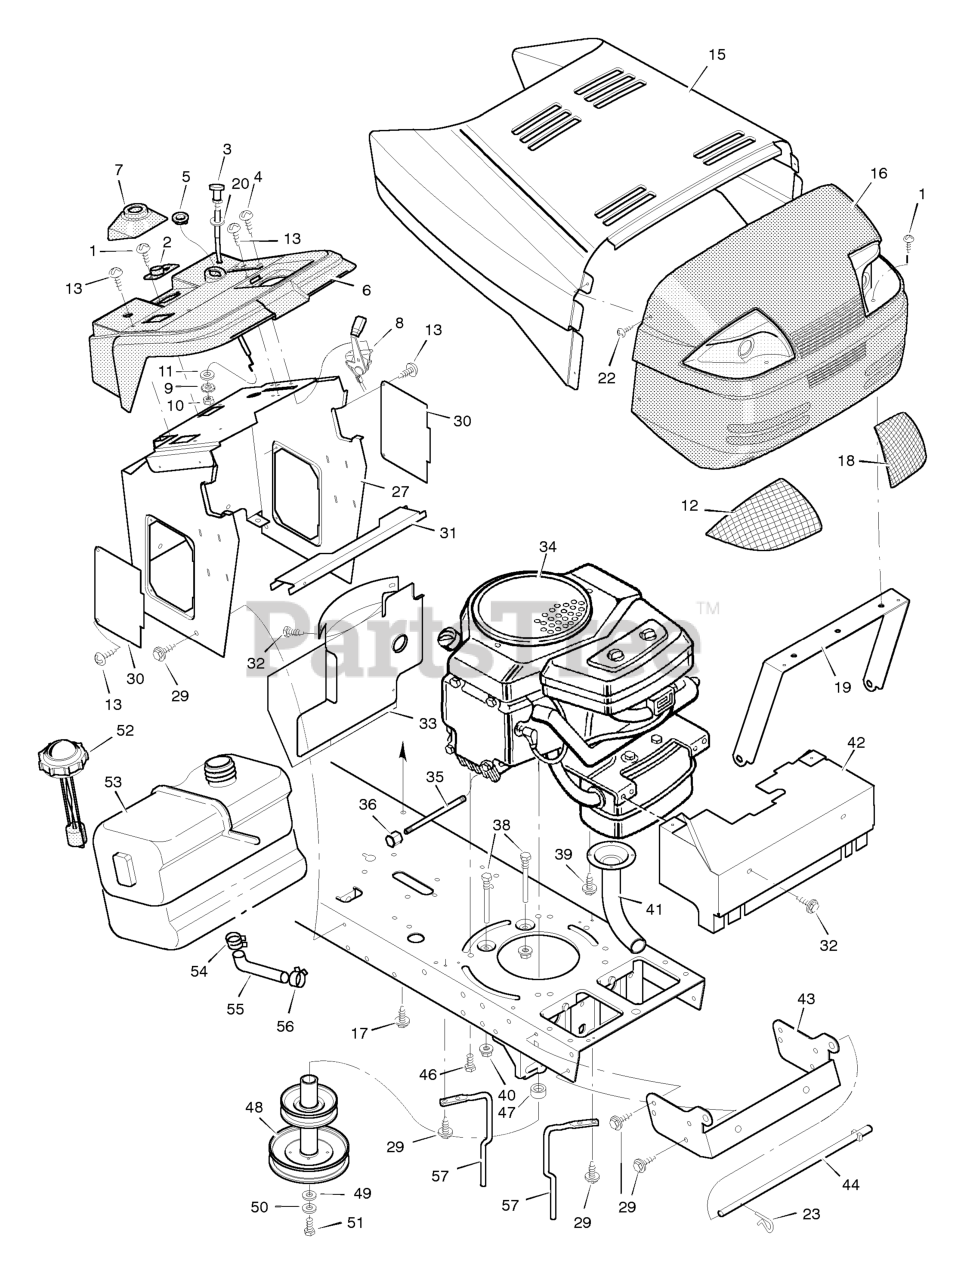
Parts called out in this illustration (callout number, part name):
2	Bearing, Steering Post
3	Cable, Choke
5	Bushing
7	Support, Bellows
8	Throttle Control
9	Lockwasher
10	Nut, Hex
11	Washer
12	Lens, Right
13	Screw
15	Hood
16	Grille
18	Lens, Left
19	Brace, Grille
20	Washer
23	Pin, Hair
27	Console Assembly
30	Panel, Side Access
31	Support, Fuel Tank
32	Screw
33	Baffle, Rear Heat
34	Engine *
35	Oil Drain Extension
36	Oil Drain Cap
38	Guide, Belt
40	Locknut, Flange
41	Pipe, Exhaust
42	Shield, Heat
43	Support, Grille
44	Rod, Pivot
46	Bolt, Hex
47	Spacer, Engine
48	Pulley Assembly, Stack
50	Lockwasher
51	Bolt, Hex
52	Cap, Fuel
53	Fuel Tank
54	Clamp, Hose
55	Fuel Line
56	Clamp, Hose
57	Guide, Belt
